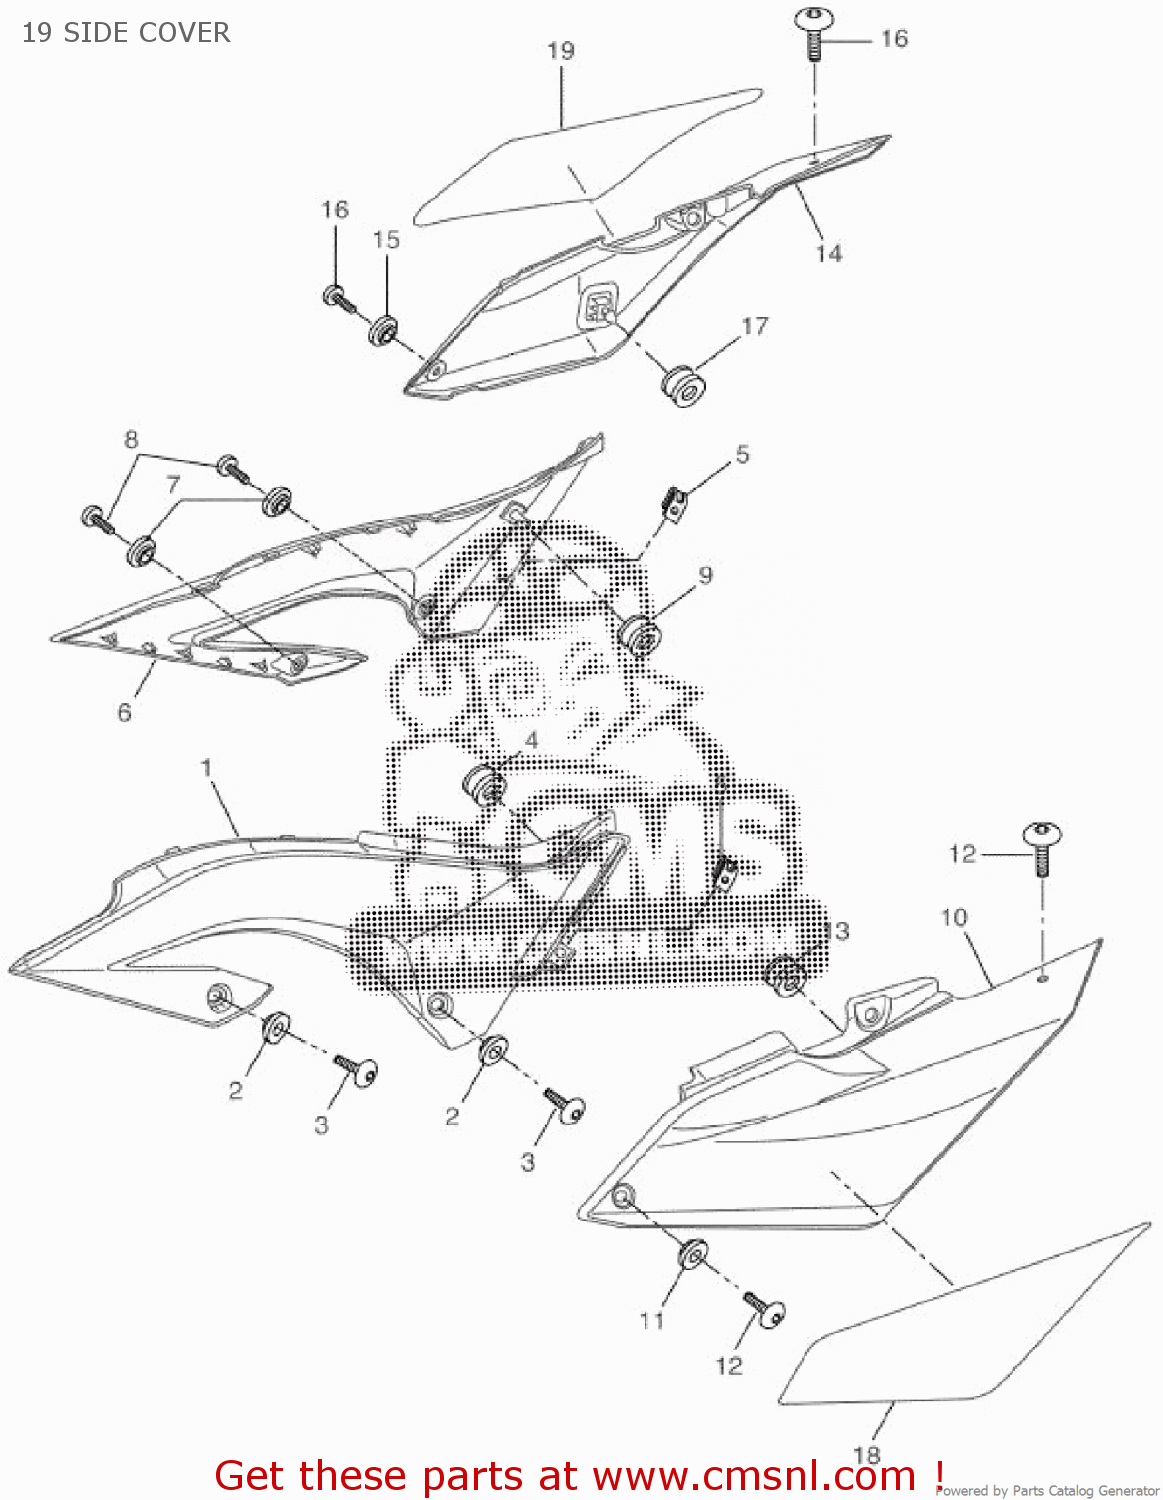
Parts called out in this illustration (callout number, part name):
1	COVER SIDE 1
2	COLLAR
3	BOLT HEX
4	GROMMET
5	NUT, SPRING
6	COVER SIDE 2
7	COLLAR
8	BOLT HEX
9	GROMMET
10	COVER SIDE 5 BLACK
11	COLLAR
12	BOLT HEX SOCKET BUTTON
13	GROMMET(4DN)
14	COVER SIDE 6
15	COLLAR
16	BOLT HEX SOCKET BUTTON
17	GROMMET(4DN)
18	GRAPHIC 1
19	GRAPHIC 2
